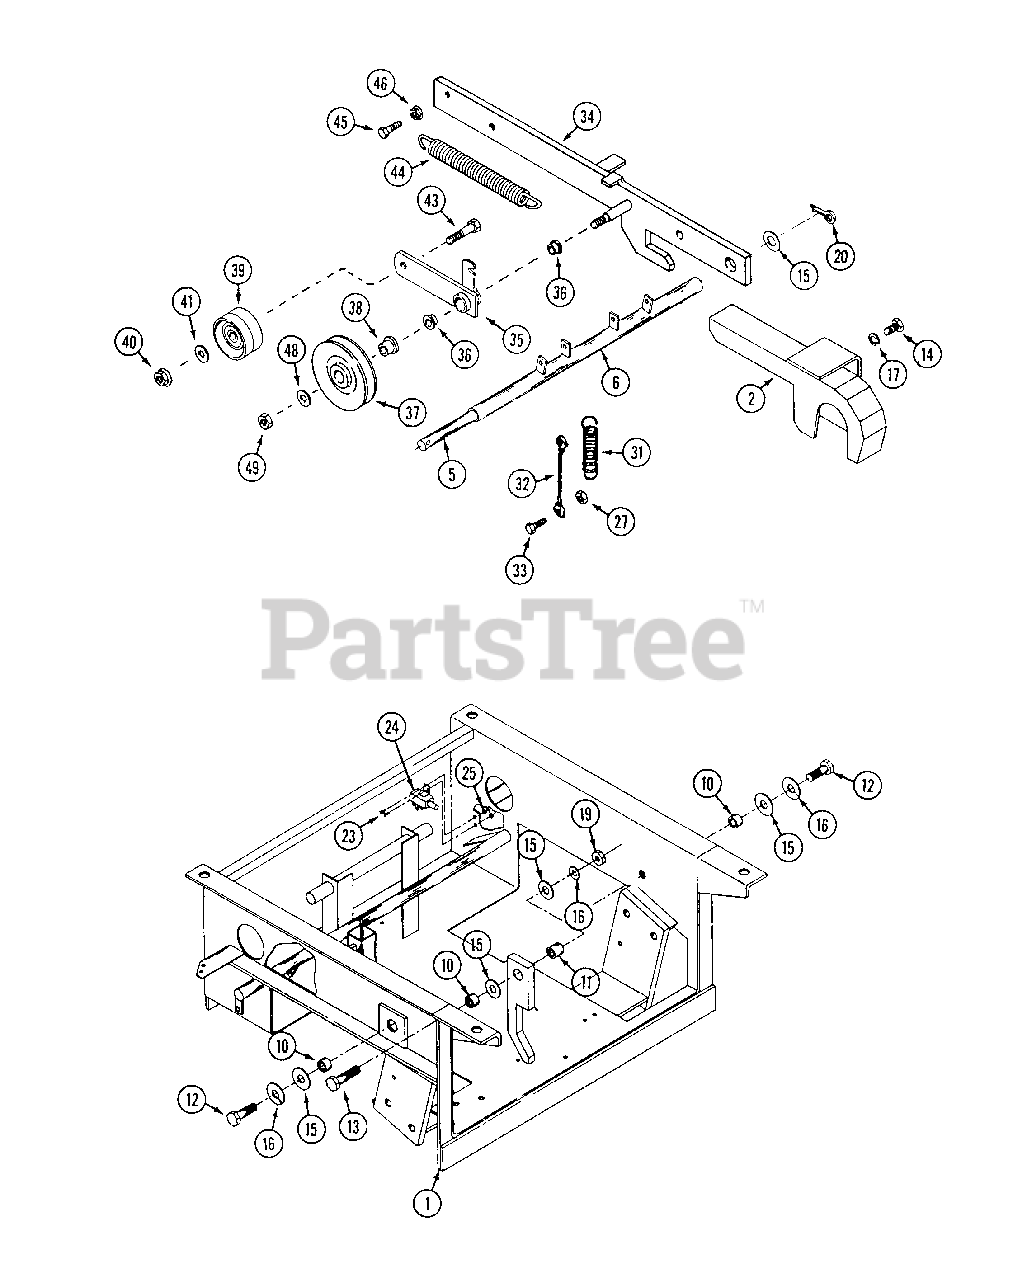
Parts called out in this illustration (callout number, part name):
5	PIN - cross bar
10	BUSHING - deck lift arm (3/8" long)
11	BUSHING - pivot (1/2" long)
12	BOLT - 1/2" - 13 x 1-1/4"
13	BOLT - 1/2" - 13 x 2-1/4"
14	BOLT - 5/16" - 18 x 3/4"
15	WASHER - 1/2"
16	LOCKWASHER - 1/2"
17	LOCKWASHER - 5/16"
19	NUT - 1/2" - 13
20	PIN - cotter 1/8" x 1"
23	SCREW - machine #10 - 32 x 5/8"
24	SWITCH - safety
25	NUT - lock #10 - 32
27	NUT - lock 1/4" - 20
31	SPRING - lift assist
33	BOLT - 1/4" - 20 x 1"
34	ARM - deck L.H.
36	BEARING - flange
37	PULLEY - "V" idler
38	BUSHING - pulley
39	PULLEY - flat
40	NUT - 3/8" - 16 lock, flange
41	WASHER - 3/8"
43	BOLT - 3/8" - 16 x 2"
44	SPRING - extension
45	BOLT - 5/16" - 18 x 1"
46	NUT - 5/16" - 18 flange lock
